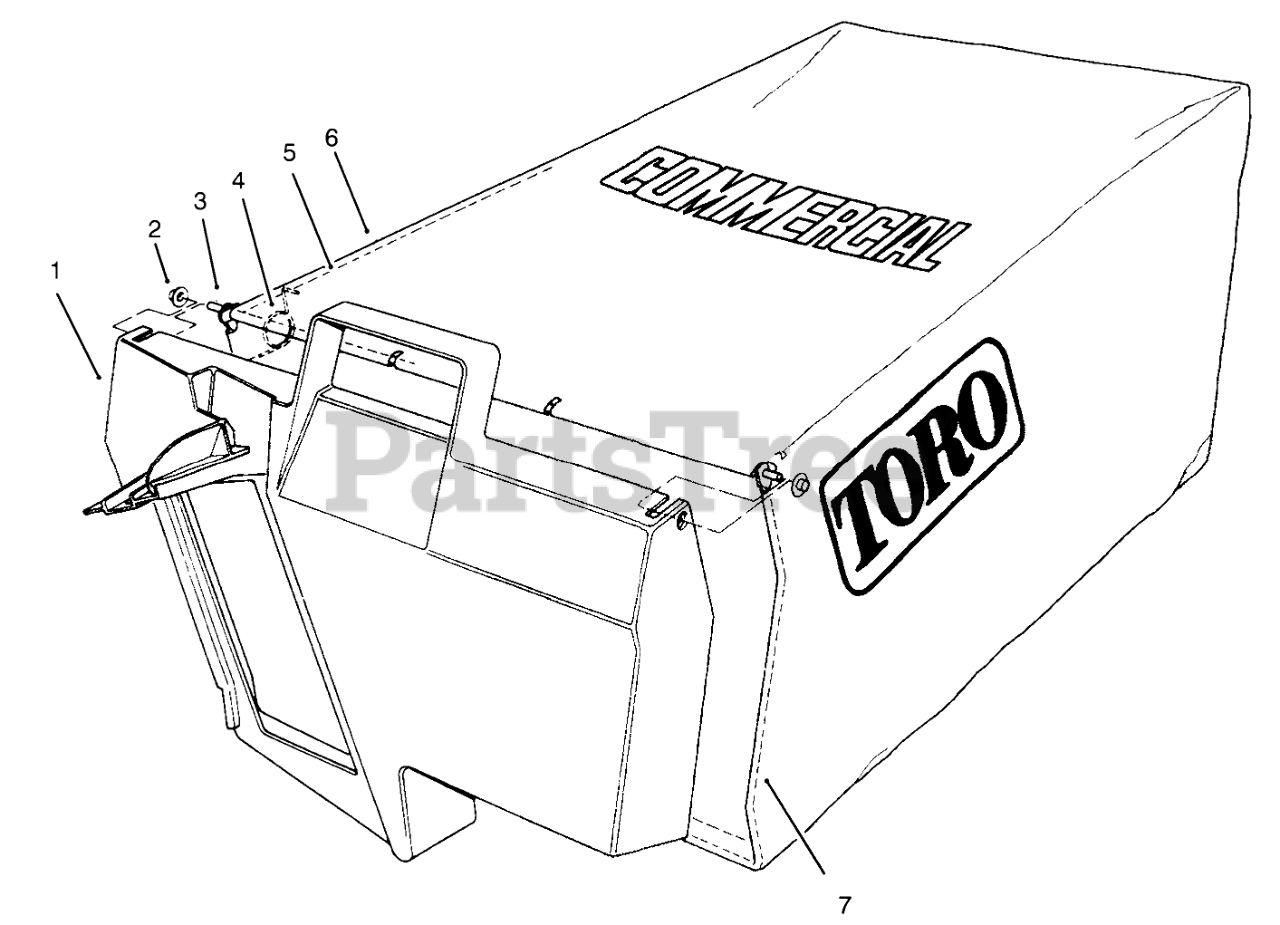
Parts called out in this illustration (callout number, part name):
1	DOOR-BAG, GRASS
2	NUT-PUSH
3	HINGE-DOOR, BAG
4	SPRING
5	FRAME-BAG, UPPER
6	Bag
7	FRAME-BAG
